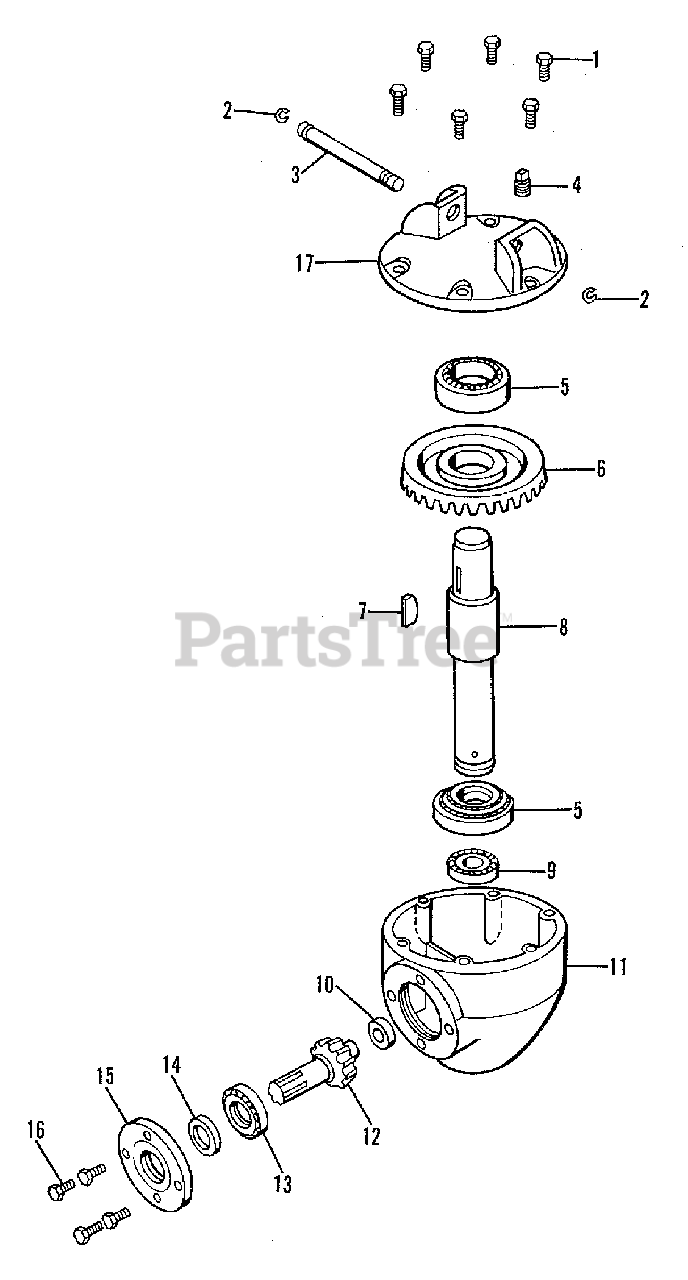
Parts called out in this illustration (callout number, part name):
1	BOLT, Cover
2	RING, Retaining
3	PIN, Suspension
4	PLUG, Filler
5	BEARING, Shaft
6	GEAR, Bevel
7	KEY, Woodruff
8	SHAFT, Output
9	SEAL, Output Shaft
10	BEARING, Input Shaft, Rear
12	PINION, Input
13	BEARING, Input Shaft, Front
14	SEAL, Input Shaft
15	HOUSING, Bearing
16	BOLT, Bearing Housing
17	COVER, Gear Case
